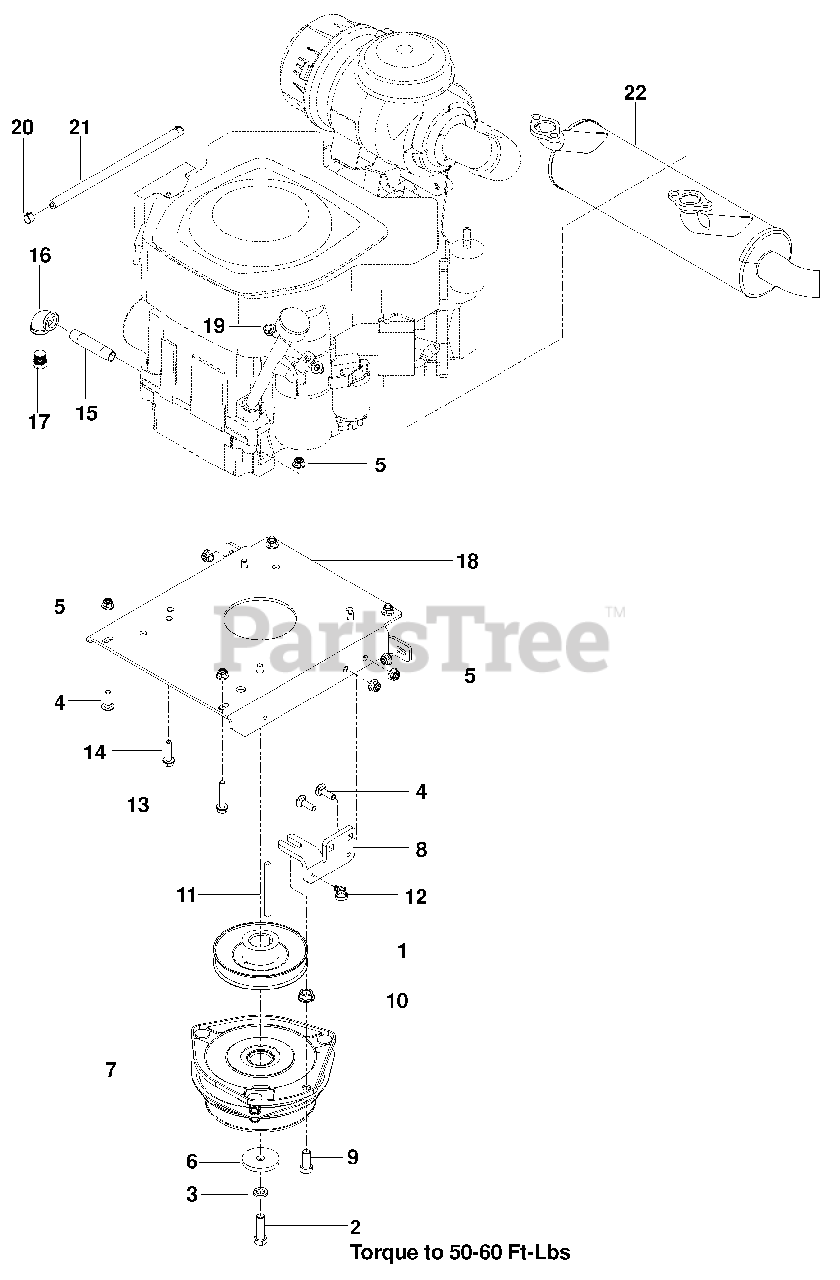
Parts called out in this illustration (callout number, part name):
1	PULLEY, ENGINE
2	Bolt 7/16-20 X 1 1/2 Hex Nyl
3	WASHER 7/16 SLW
4	BOLT 5/16-18 x 1 RD HD
5	NUT 5/16-18 HEX FLG NYLOC
6	WASHER, BLADE
7	CLUTCH, GT 3.5
8	STOP, CLUTCH
9	BOLT 7/16-14 x 1 HEX NYLOC
10	NUT 7/16-14 HEX WHIZ LK
11	KEY, 1/4 SQ x 3 1/2
12	TIE WRAP w/ CLIP
13	SCREW 5/16-18 x 2 1/4 HEX FLG
14	SCREW 5/16-18 x 1 1/2 HEX FLG
15	PIPE 3/8 NPT x 3"
17	PLUG, DRAIN, 3/8 NPTF
18	PLATE, ENGINE
19	SCREW 5/16-18 x 3/4 HEX FLG
20	CLAMP, HOSE
21	FUEL LINE 5"
